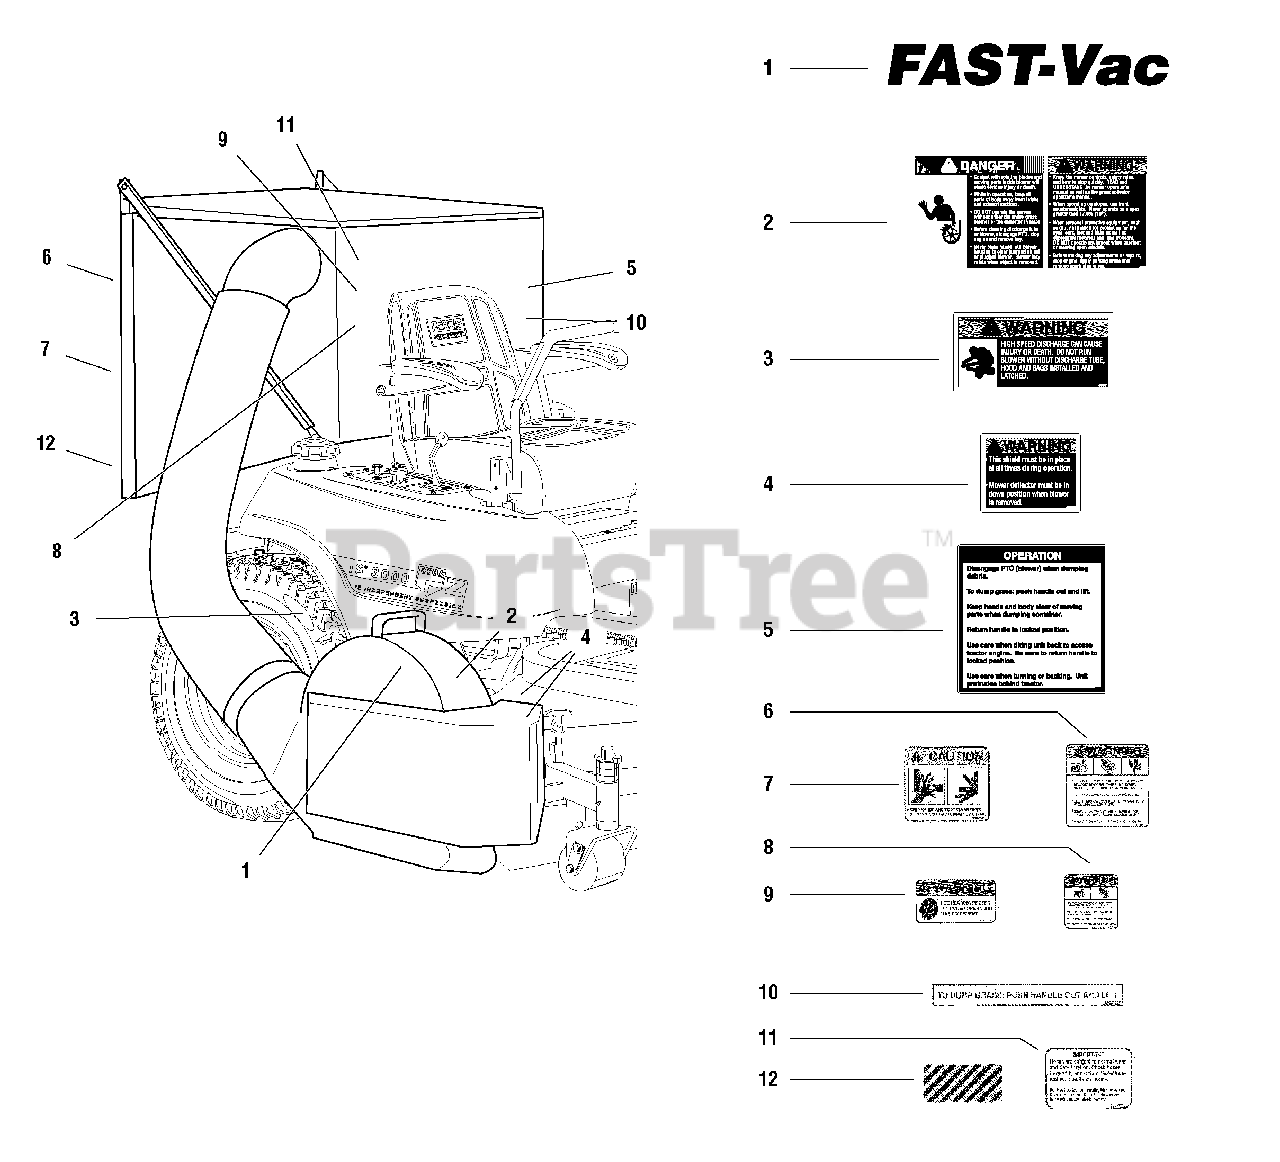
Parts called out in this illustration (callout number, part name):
1	DECAL, Fast-Vac
2	DECAL, Danger/Warning
3	DECAL, Warning-Blower
4	DECAL, Warning-Shield
5	DECAL, Operation
6	DECAL, Warning
7	DECAL, Caution
8	DECAL, Warning
9	DECAL, Warning
10	DECAL, Dump Grass
11	DECAL, Tube Wear
12	DECAL, Strip
